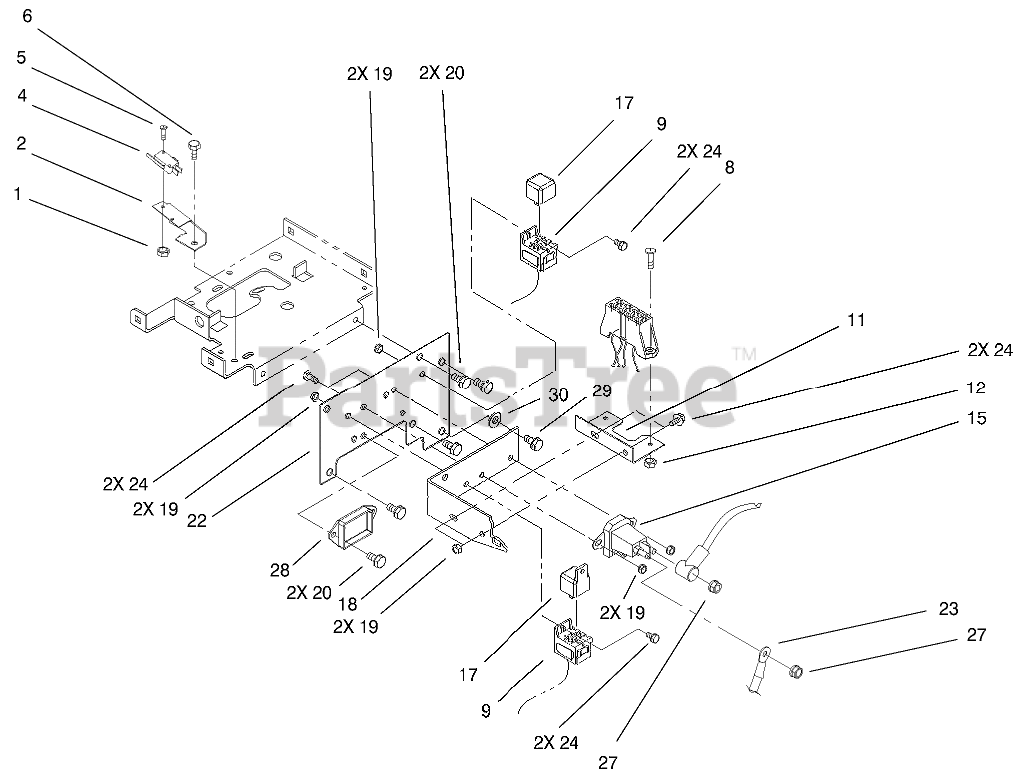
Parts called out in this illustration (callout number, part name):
1	NUT-HEX
2	BRACKET-SWITCH
4	SWITCH
5	SCREW-PPH
6	SCREW-HWH
8	SCREW-PAN
9	Harness-Wire 14 HP (only on: 73449)
9	Harness-Wire 12 HP (only on: 73429)
11	FUSE HOLDER
12	NUT-LOCK, NI
15	SOLENOID
17	RELAY
18	BRACKET-BELT
19	NUT-LOCK, NI
20	SCREW-HWHTF
22	PLATE-HOODSTAND, FRONT
23	CABLE-BATTERY, POSITIVE
24	SCREW-HHF
27	NUT-KEPS
28	MODULE
29	SCREW-HWHTF
30	WASHER-FLAT
